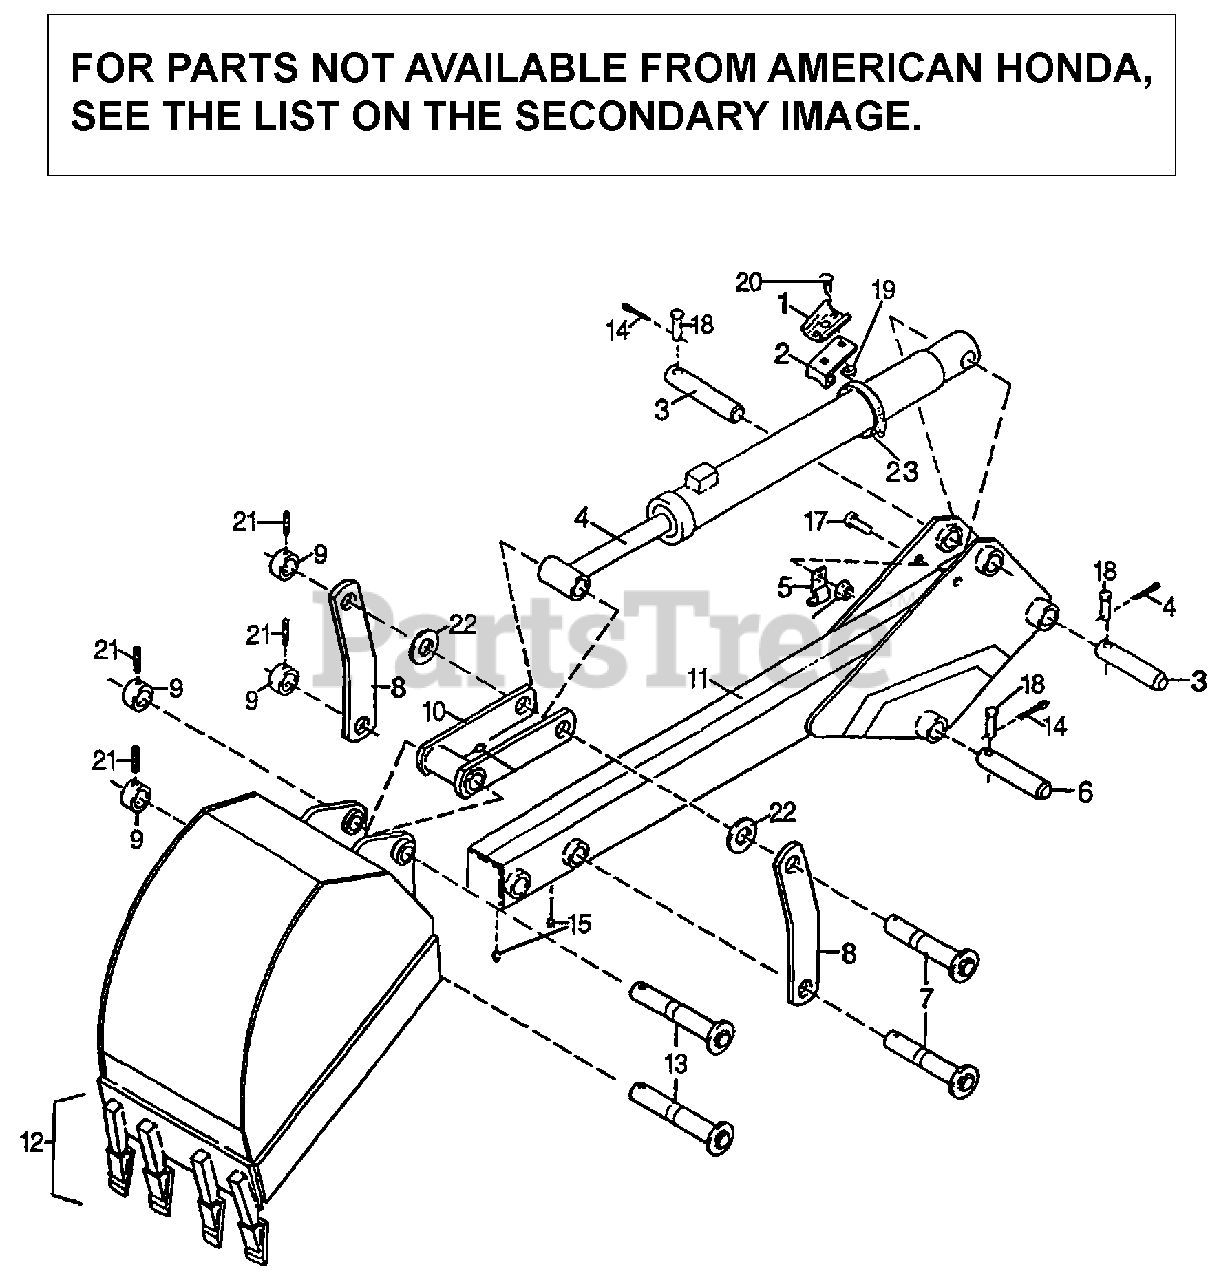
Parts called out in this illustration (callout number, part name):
1	SOCKET, SMV EMBLEM
2	BRACKET, SMV EMBLEM
3	PIN, PIVOT
4	CYLINDER, HYDRAULIC (2X16-3/4)
5	CLAMP, HOSE
7	PIN, ROTATING PIVOT
8	ARM, LINK
9	SLEEVE, RETAINING PIVOT PIN
10	ARM, BUCKET
11	WELDMENT ASSY., DIPPERSTICK
12	SHANK & TOOTH ASSY.
13	PIN ASSY., PIVOT (1.0X7.25)
23	CLAMP, HOSE
